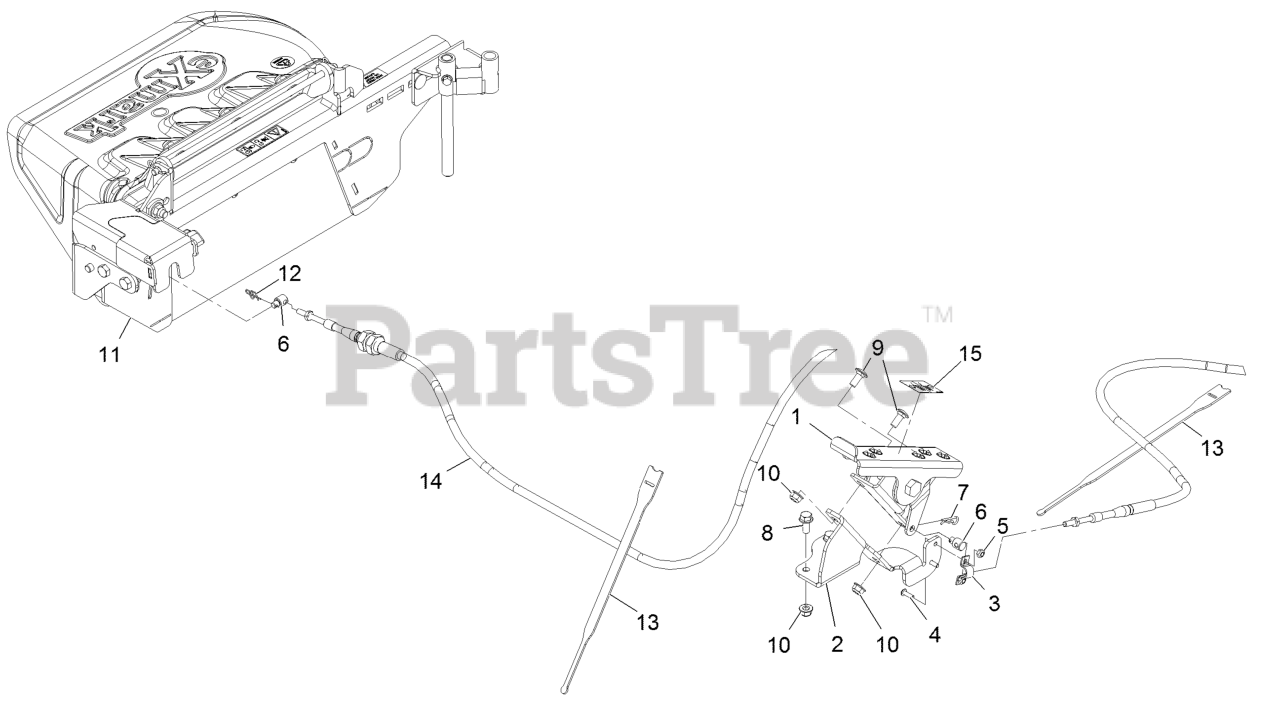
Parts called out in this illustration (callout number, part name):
1	ASM, Pedal, Ocd Gate
2	Mount-Pedal, Ocd
4	Screw-HSBH
5	Nut-Nyloc #10-24 Thin
6	Pivot, Control Cable
7	Hairpin-Cotter
8	Screw-HH Flg 5/16-18 X 3/4
9	Bolt-Carriage 5/16-18 X 3/4 Short Neck
10	Nut-Nyloc 5/16-18 Flg
11	ASM, Ocd
12	Pin-Cotter, Locking
13	Strap-Velcro, Cable Tie
14	Cable-Discharge Gate
15	Decal-Ocd Operation
